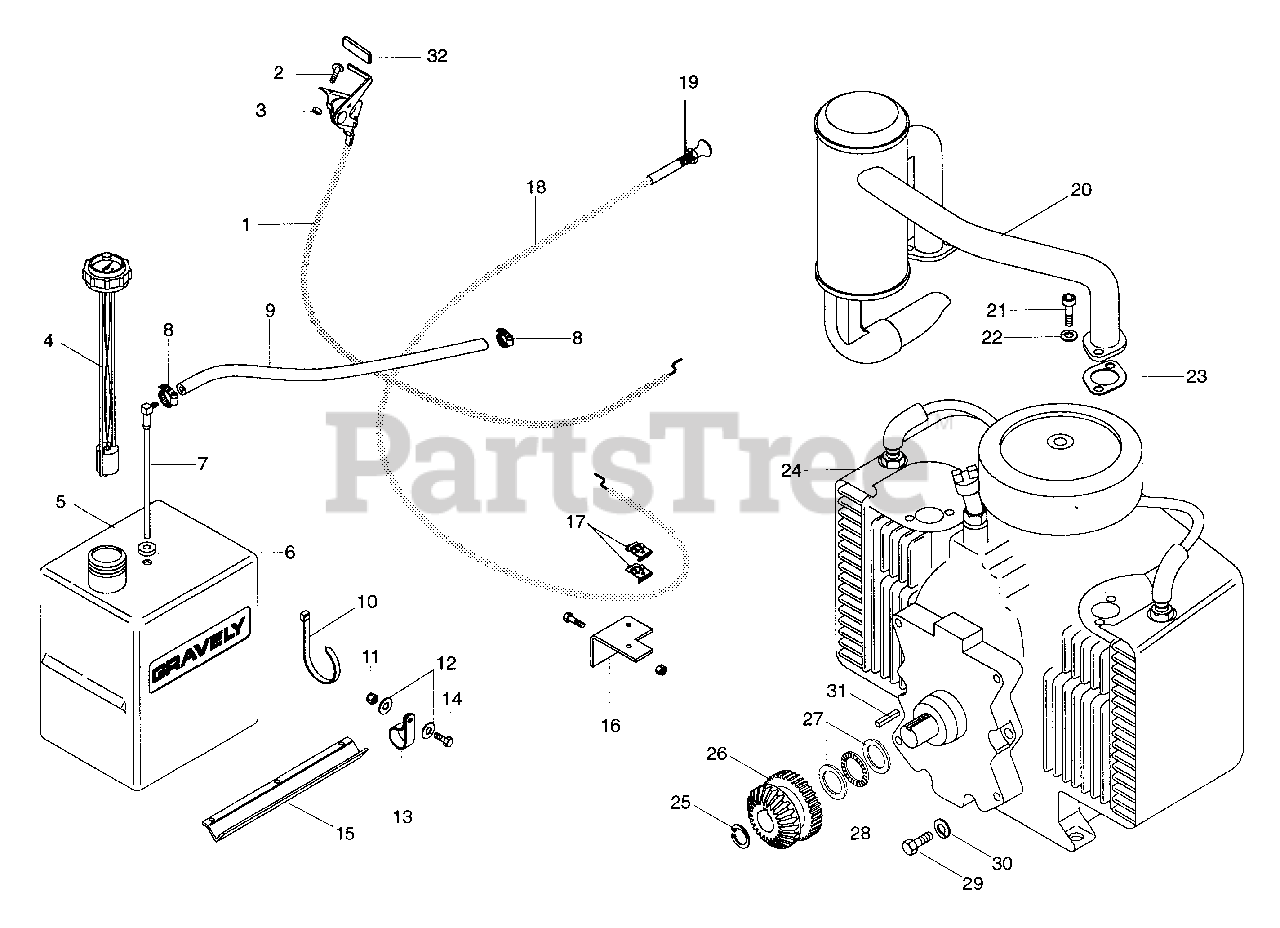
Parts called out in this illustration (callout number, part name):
1	Throttle Cable
2	Screw-Machine 10-32 x .50
3	Nut-Locking 10-32
4	Gauge, Fuel
5	Tank, Fuel
6	Bushing
7	Fitting, Tank
8	Hose Clamp
9	Gas Line - Bulk
10	Tie, Cable
11	Nut-Locking-Nylon .312-18 Grade 2
12	Washer-Flat-Steel .344 x .688 x .065
13	Cable Clamp
14	Bolt-Hex .31-18 x 1.00 Grade 5
15	Shield, Heat
16	Bracket, Throttle & Choke
17	Clip, Speed
18	Control, Choke
19	Nut-Jam .375-24
20	Muffler, Exhaust
21	Screw-Cap .31-18 x .75
22	Washer-Lock .313 x .078
23	Gasket, Exhaust
24	Engine, 16 HP Magnum, PS-24633
24	Engine, 18 HP Magnum, PS-24590
24	Engine, 20 Hp S.B. Kohler PT .49562
25	Ring-Retaining 1.249 x .050
26	Gear, Spur & Bevel
27	Washer-Thrust 1.125 x 1.750 x .123
28	Bearing-N-Thrust 1.84 x 1.127 x .078
29	Bolt-Hex .50-13 x 1.75
30	Washer-Lock .50 Reg
31	key, Square .248 x 1.25 x .248
32	Grip
